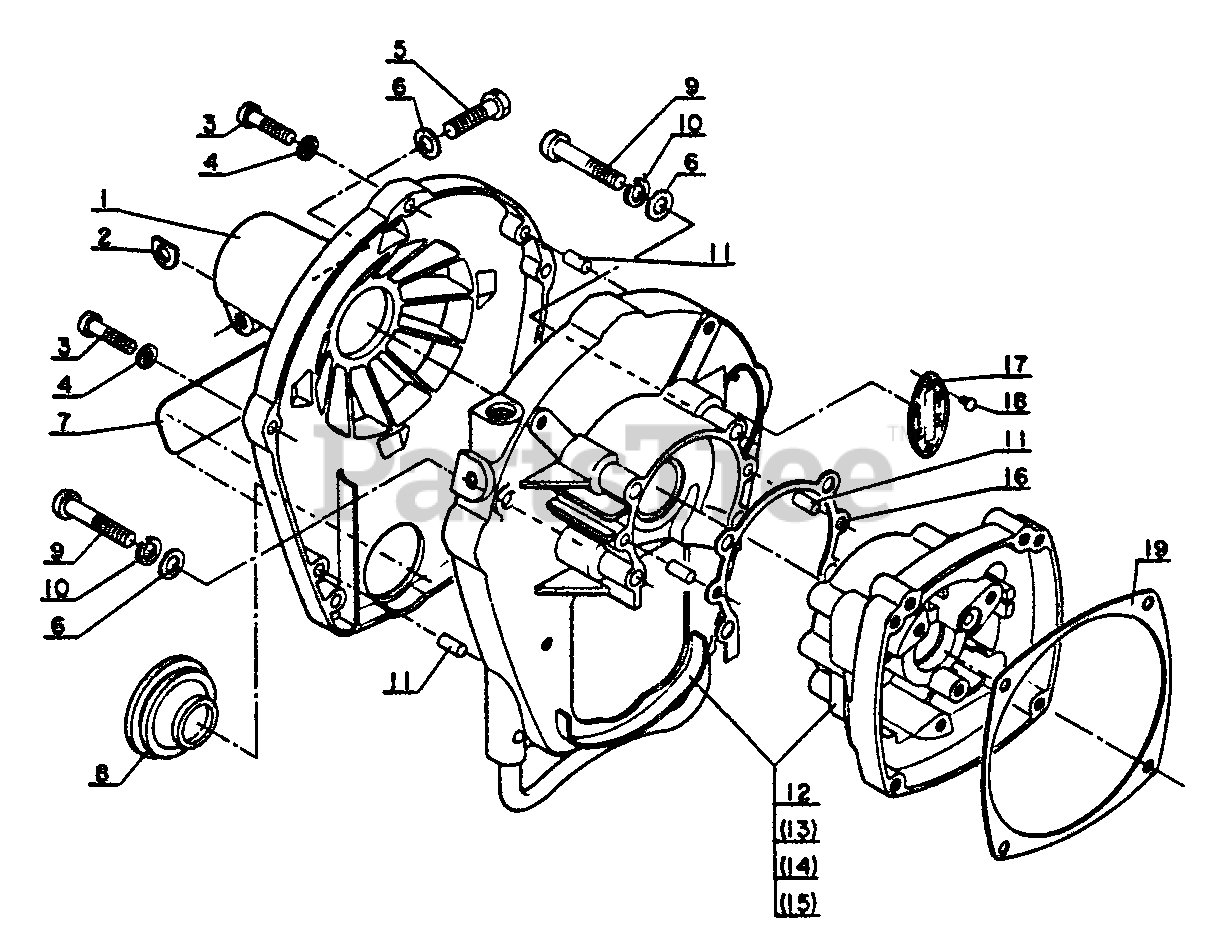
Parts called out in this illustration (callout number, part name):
1	CASE, FAN
3	SCREW - 4×18
4	WASHER 4 MM
5	BOLT - 5×20
6	WASHER, FLAT 5.5×10×0.8
7	NAME PLATE
8	COVER, SPARK PLUG
9	SCREW - 5×18
10	WASHER, SPRING 5
11	PIN, LOCATING 4
12	CRANKCASE KIT
14	STAND
16	GASKET, CRANKCASE
17	MODEL PLATE
18	RIVET
19	GASKET, STARTER
